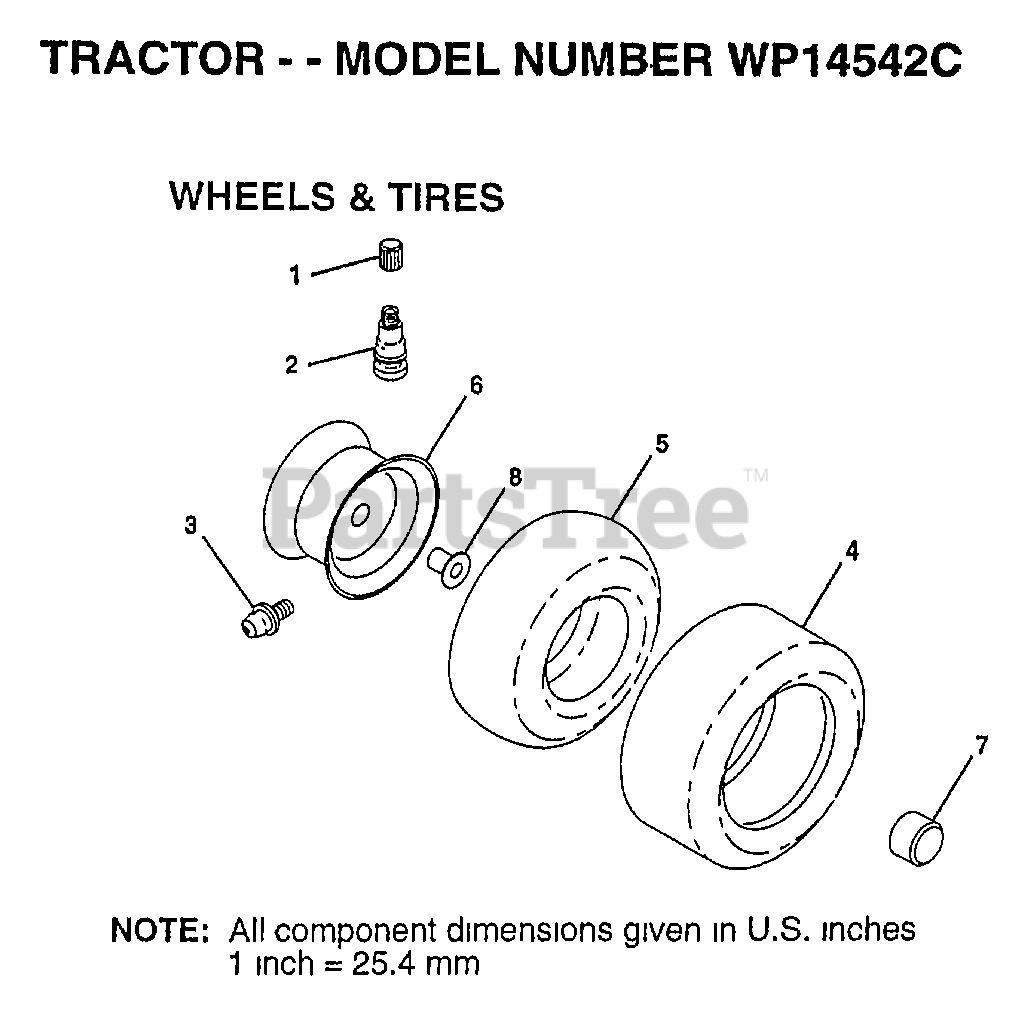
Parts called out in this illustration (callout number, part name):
1	VALVE CAP
2	VALVE STEM LT
3	FITTING LT
4	TIRE.20X8-8
5	TUBE.5.3/4.5/6
5	TUBE.18X9.5-8
6	"RIM,FRT T"
6	"RIM 8"""
7	HUB CAP
8	"FLANGE, BEARING"
